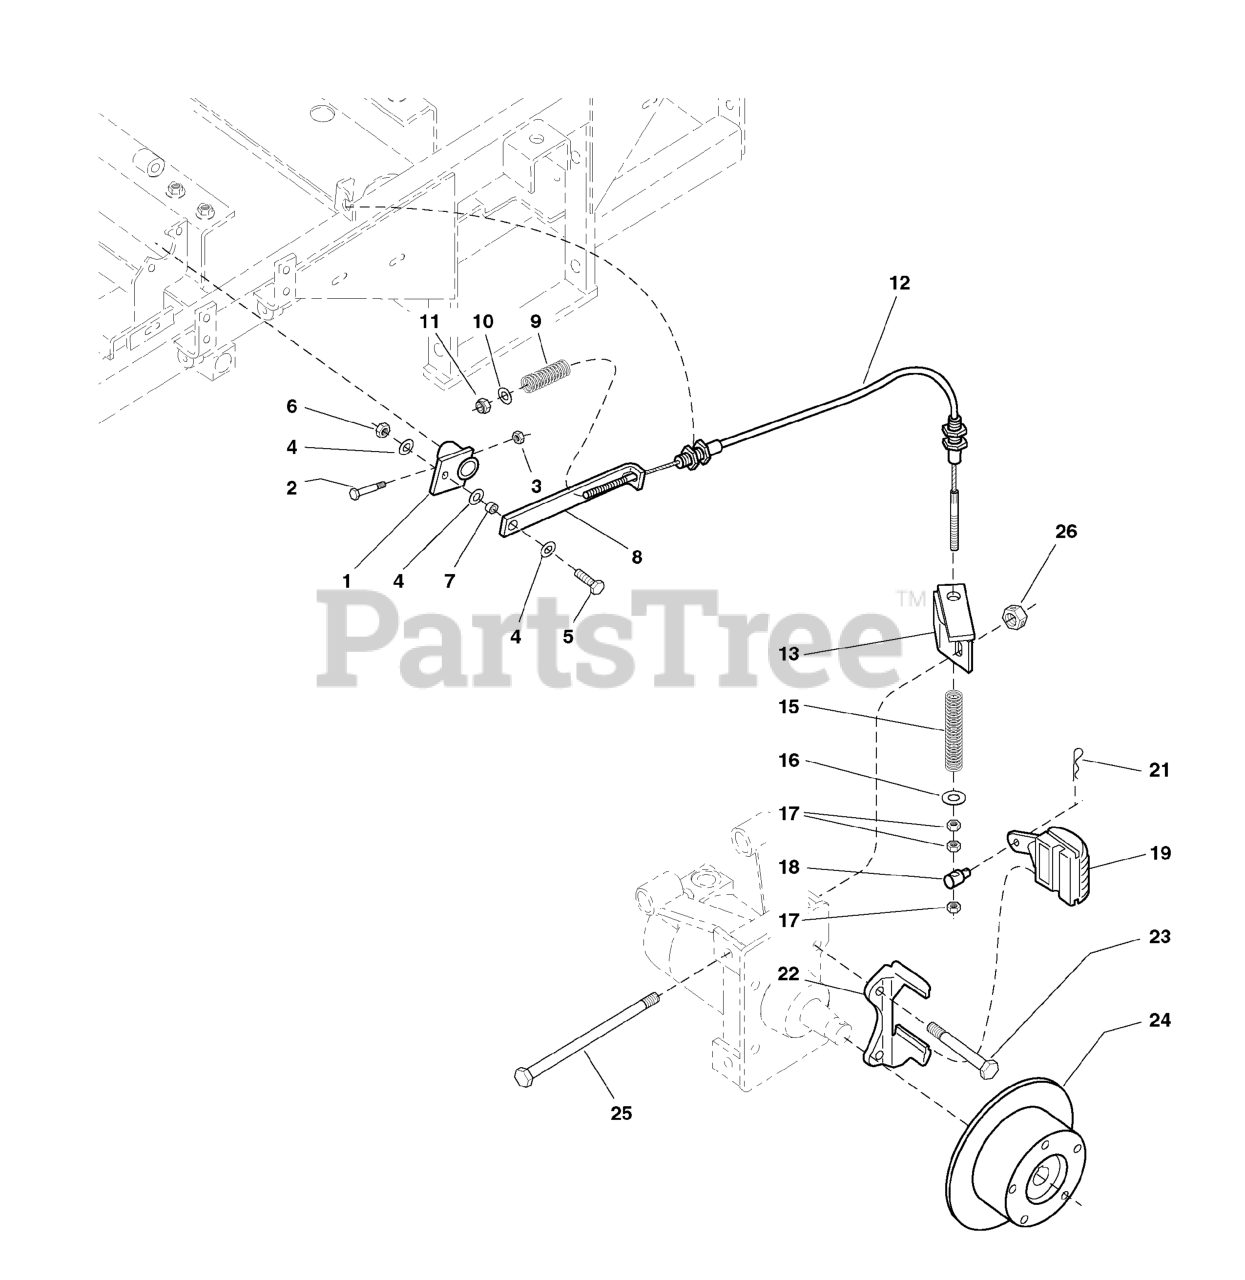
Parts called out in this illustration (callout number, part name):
1	PIVOT, LINKAGE MOUNT WELDMENT - BLK
2	BOLT, 1/4-20 x 1-3/4
3	NUT, 1/4-20 HEX NYLON LOCK
4	WASHER, 3/8 SAE
5	BOLT, 3/8-16 X 1-1/4" GD5 CZ
6	NUT, 3/8-16 HEX NYLON LOCK
7	SPACER, .38 x .50 x .27
8	LINK, Brake Lock
9	SPRING, Compression
10	WASHER, 5/16" SAE
11	NUT, 5/16-24 HEX NYLON LOCK
12	CABLE, Brake
13	BRACKET, Cable Mount-LH
15	SPRING, Compression
16	WASHER, 5/16" Fender
17	NUT, 5/16-24 Hex
18	ADJUSTER, Brake Linkage
19	BRAKE CALIPER, LH
21	HAIRPIN CLIP
22	MOUNT, Brake Caliper
23	BOLT, 1/2-20 x 3
24	HUB, 8" Brake Disc
25	BOLT, 1/2-13 x 6-1/2
26	NUT, 1/2-13 Hex Side Lock
27	KIT, BRAKE PAD REPLACEMENT
